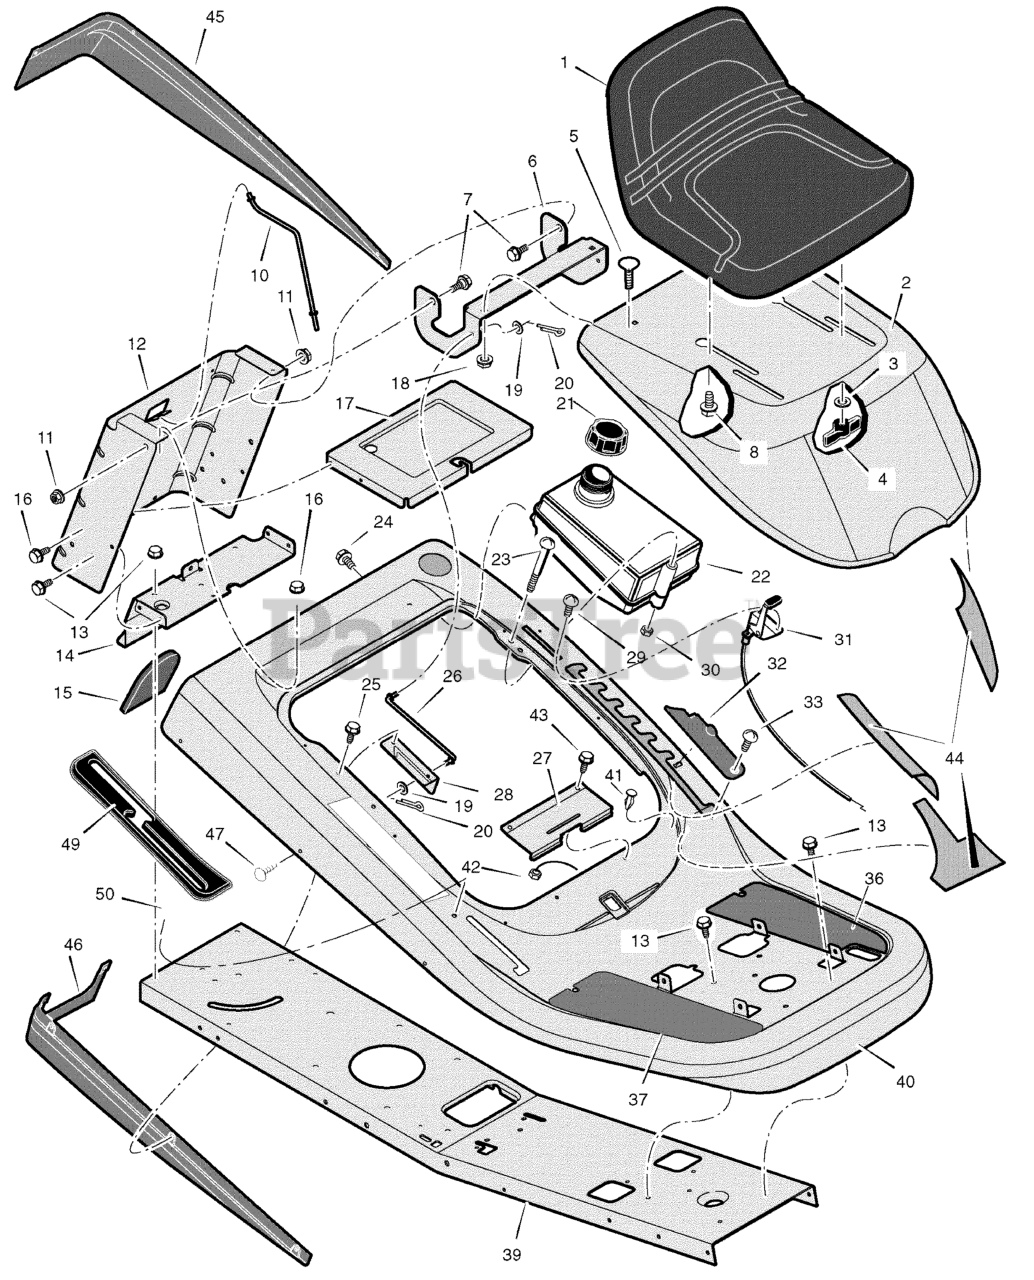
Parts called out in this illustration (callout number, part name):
3	Washer
4	Bolt, Wing
5	Bolt, Carriage
6	Bracket, Hinge
7	Bolt, Shoulder
8	Bolt, Shoulder
10	Rod, Battery
11	Nut, Flange
12	Plate, Rear
13	Screw
14	Plate, Hitch
16	Screw
17	TRAY, Battery
18	Nut, Flange
19	Washer
20	Pin, Hair
21	Cap, Fuel Tank *
22	Tank, Fuel
23	Screw *
25	Screw
26	Rod, Hood Prop
27	Spring, Seat Deck
28	Bracket, Prop Rod
29	Screw
30	Nut, NY-Lock
31	Control, Throttle
32	Cover, Detent (Black)
33	Bolt, Shoulder
36	Footmat, Left (Black)
37	Footmat, Right (Black)
40	Deck, Seat
41	Bumper
43	Screw
44	Kit, Foil Heat Shield
45	Trim, Left
46	Trim, Right
47	Fastener, Panel
49	Cover, Long Black
50	Nut, Push
